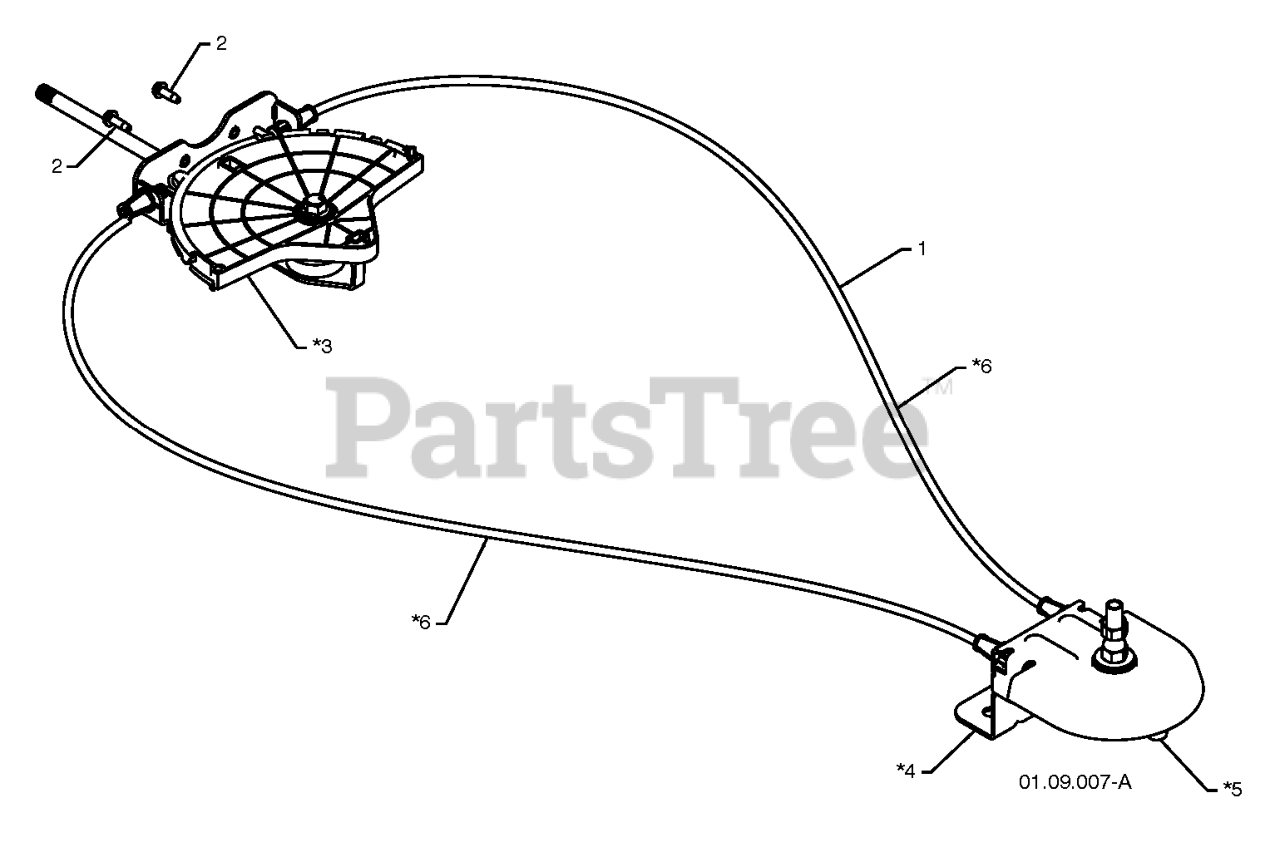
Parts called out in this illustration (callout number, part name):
1	RP.LEVER/CABLE.ASM.ROTATOR
2	SCREW #10-24 X 5/8
3	CHUTE.ROT.HEAD.SERVICE
4	SNOW.PIVOT.BRKT.BLK.SERVICE
5	SNOW.PIVOT.PULLY
6	CABLE.ASSEMBLY.DISCHARGE.SNOW
